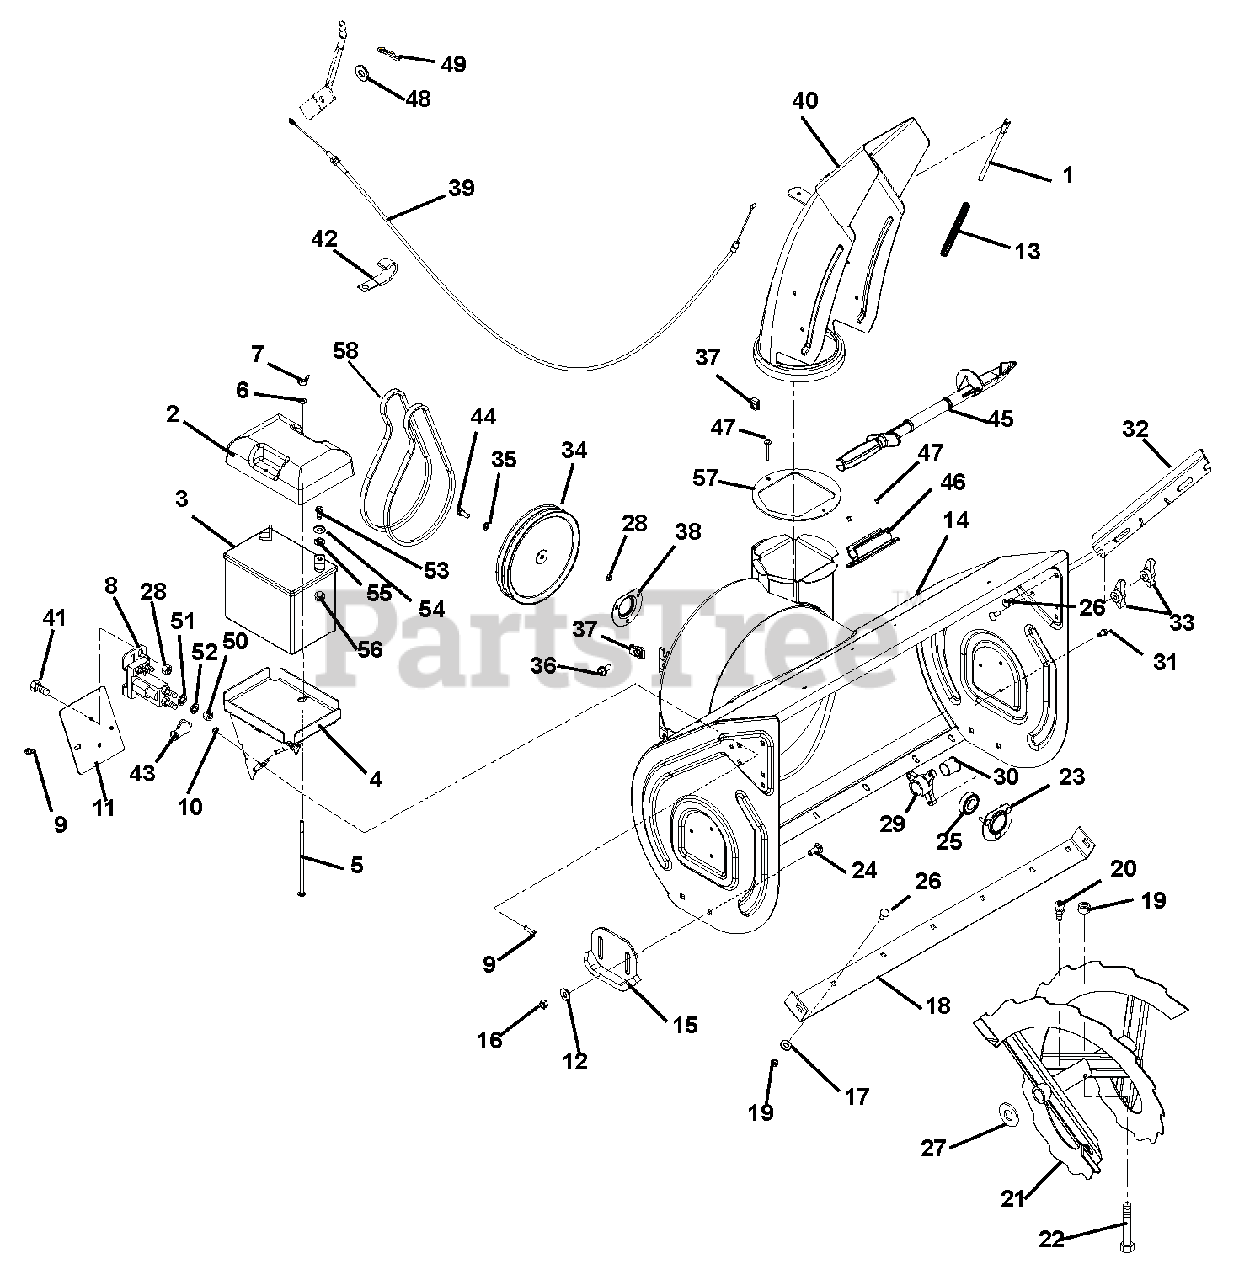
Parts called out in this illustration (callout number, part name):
1	ROD, DEFLECTOR CAP
2	COVER, BATTERY
4	TRAY, BATTERY-W/CLIPS
5	@BLT-RDHDSQNK .25-20X7.00 G2YZ
6	@WSHR-FL-STL.281X.62X.065 YWZC
7	NUT-LK WING .250-20 YWZC
8	SOLENOID
9	BLT-HEX .25-20X.75 HWH YZ GR5
10	NUT-RTNR .25-20X.56
11	COVER, SOLENOID
12	@WSHR-FL-STL.438X1.00X.083 YWZ
13	SG-COMP .08X.40X6.50 14#/IN
14	HOUSING, BLOWER-26" W/DECAL
14	HOUSING, BLOWER-28" W/DECAL
14	HOUSING, BLOWER-32" W/DECAL
14	HOUSING, BLOWER-32"B W/DECAL
14	HOUSING, BLOWER-36"B W/DECAL
15	RUNNER, SKID SHOE-1/2" FLANGE
15	SKID SHOE, REVERSIBLE - ORANGE
16	@NUT-LK-CTR .38-16 YWZC
17	@WSHR-FL-STL.438X1.00X.083 YWZ
17	@WSHR-FL-STL.38X.875X.083 YWZC
18	BLADE, SCRAPER-26"
18	BLADE, SCRAPER-28"
18	BLADE, SCRAPER-32"
18	BLADE, SCRAPER-36"
19	@NUT-LK-CTR .31-18 YWZC
20	FTG-LUBE .25-28X.256 YWZC
21	RAKE, LH-26"(1 ID X 15.75 OD)
21	RAKE, RH-26" (1 ID X 15.75 OD)
21	RAKE, LH-28" (1 ID X 15.75 OD)
21	RAKE, RH-28" (1 ID X 15.75 OD)
21	RAKE, LH-32" (1 ID X 15.75 OD)
21	RAKE, RH-32" (1 ID X 15.75 OD)
21	RAKE, LH-36" (1ID X 15.75 OD)
21	RAKE, RH-36" (1 ID X 15.75 OD)
22	SHEAR BOLT SERVICE ASSEMBLY
23	BEARING FLANGE
24	@BLT-RDHDSHSQNK.38-16X1.0 G5YZ
25	BRG-BALL .876 X 1.750 X .50
26	@BLT-RHDSSQNK .31-18X.75 G5YZ
27	WSHR-FL-STL 1.010X1.505X.062YZ
28	@NUT-LK-CTR .25-20 YWZC
29	BUSHING, RAKE SHAFT 1"
30	BSHG-FLG, SPLIT NYLINER 1.0"ID
31	@SCR-TAP .25-20X.50 HWH TR YWZ
32	CUTTER, DRIFT
33	KNOB - WING .312-18 UNC
34	PULLEY,2X4LX8.5 BOLTED
35	WSHR-LK .312X.097 HVY YWZC
36	BLT-SERHFWH .38-16X.75 YWZC
37	NUT-RTNR .375-16X.37
38	BEARING FLANGE
39	CABLE, DEFLECTOR
40	CHUTE, DISCHARGE-W/DEFLECTOR
41	@BLT-HEX .25-20X.50 GR5 YWZC
42	J-CLAMP
43	BOOT, EYELET TERMINAL
44	BLT-HEX .31-24X.75 YWZC GR5
45	DEVICE, SNOW CLEAN OUT
46	MOUNT, SNOW CLEAN OUT
47	RVT-POP .187 YZ
48	@WSHR-FL-STL.281X.62X.065 YWZC
49	PIN-HAIR INT .06X.18X.77
50	NUT-JAM .31-24 YWZC
51	WSHR-LOCK INT .31 YWZC
52	@WSHR-LK .31X.078 REG YWZC
53	@BLT-HEX .25-20X.75 GR5 YWZC
54	WSHR-FL-STL .265X.50X.087YWZC
55	@WSHR-LK .25X.062 REG YWZC
56	@NUT-HEX .25-20 YWZC
57	BAFFLE, DISCHARGE NECK
58	V-BELT, HA-RAW EDGE (SET)
